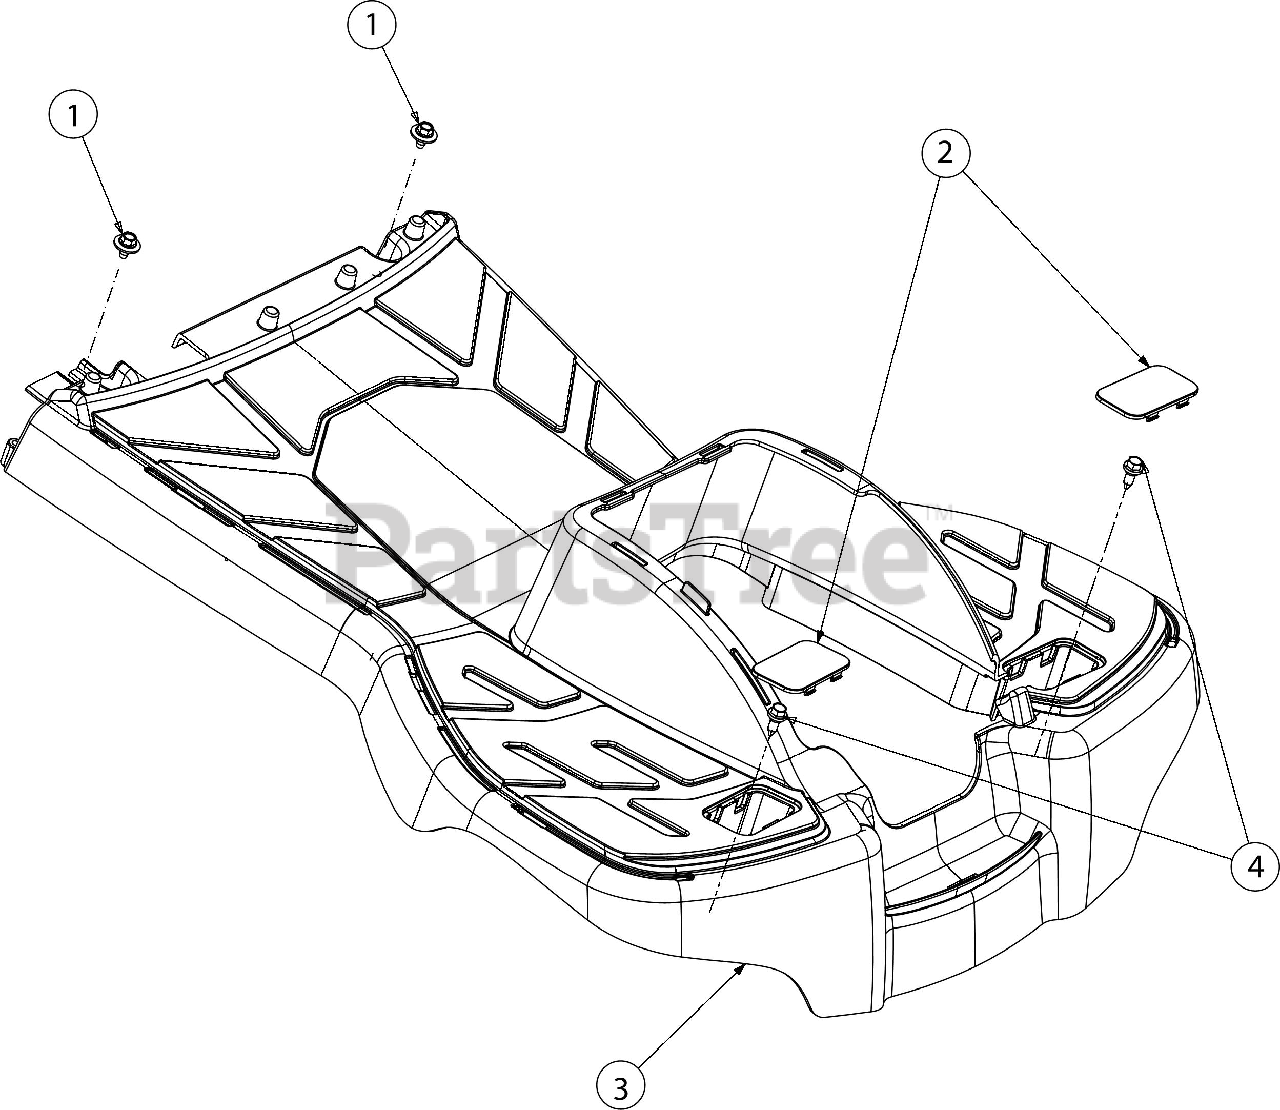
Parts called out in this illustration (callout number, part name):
1	SCREW 1/4-20 x .50
2	RUNNING BOARD PLUG
3	RUNNING BOARD
4	SHOULDER SCREW
